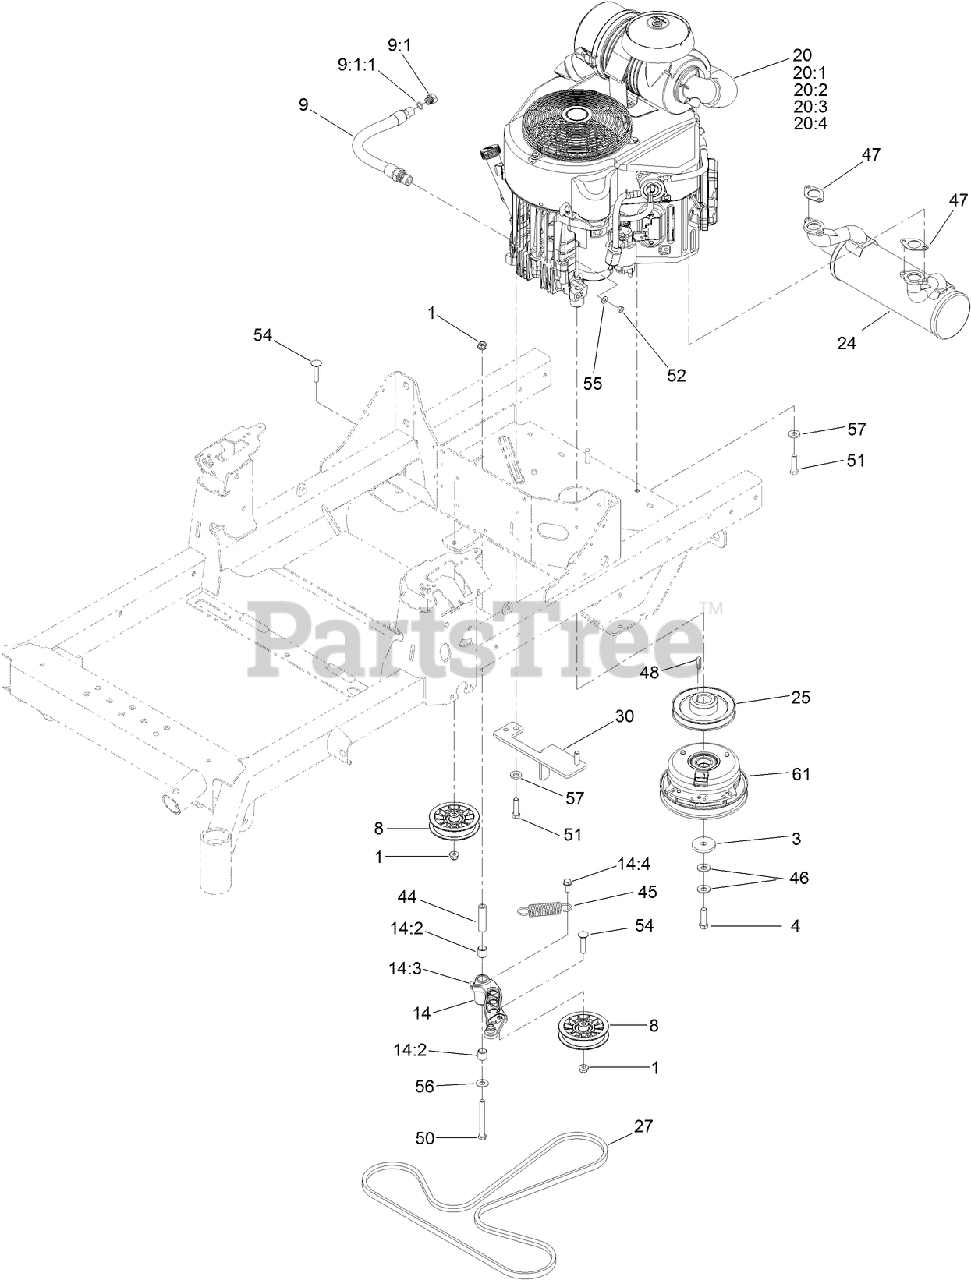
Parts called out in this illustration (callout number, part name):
1	NUT-HF, NI
3	WASHER-CLUTCH
4	SCREW-HH
8	PULLEY-FLAT
9	ENGINE OIL DRAIN HOSE ASM
9:1	PLUG-HH
9:1:1	O-RING
14	IDLER ARM ASM
14:2	SLEEVE-BEARING
14:3	FITTING-GREASE, 90 DEG
14:4	SCREW-HWHTF
20:1	KAWASAKI 49065-7007 ENGINE OIL FILTER
20:2	KAWASAKI 49019-7005 FUEL FILTER
20:3	KAWASAKI 11013-7045 SAFETY FILTER
20:4	KAWASAKI 11013-7044 ENGINE AIR FILTER
24	MUFFLER
25	SHEAVE (W/HUB)
27	BELT-V
30	ANCHOR-CLUTCH
44	BUSHING-PIVOT, IDLER
45	SPRING-EXTENSION
46	WASHER-SPRING
47	GASKET-EXHAUST
50	SCREW-HH
51	SCREW-HH
52	NUT-HEX
54	SCREW-CARR
55	WASHER-FLAT
56	WASHER-FLAT
57	WASHER-BELLEVILLE
61	CLUTCH
